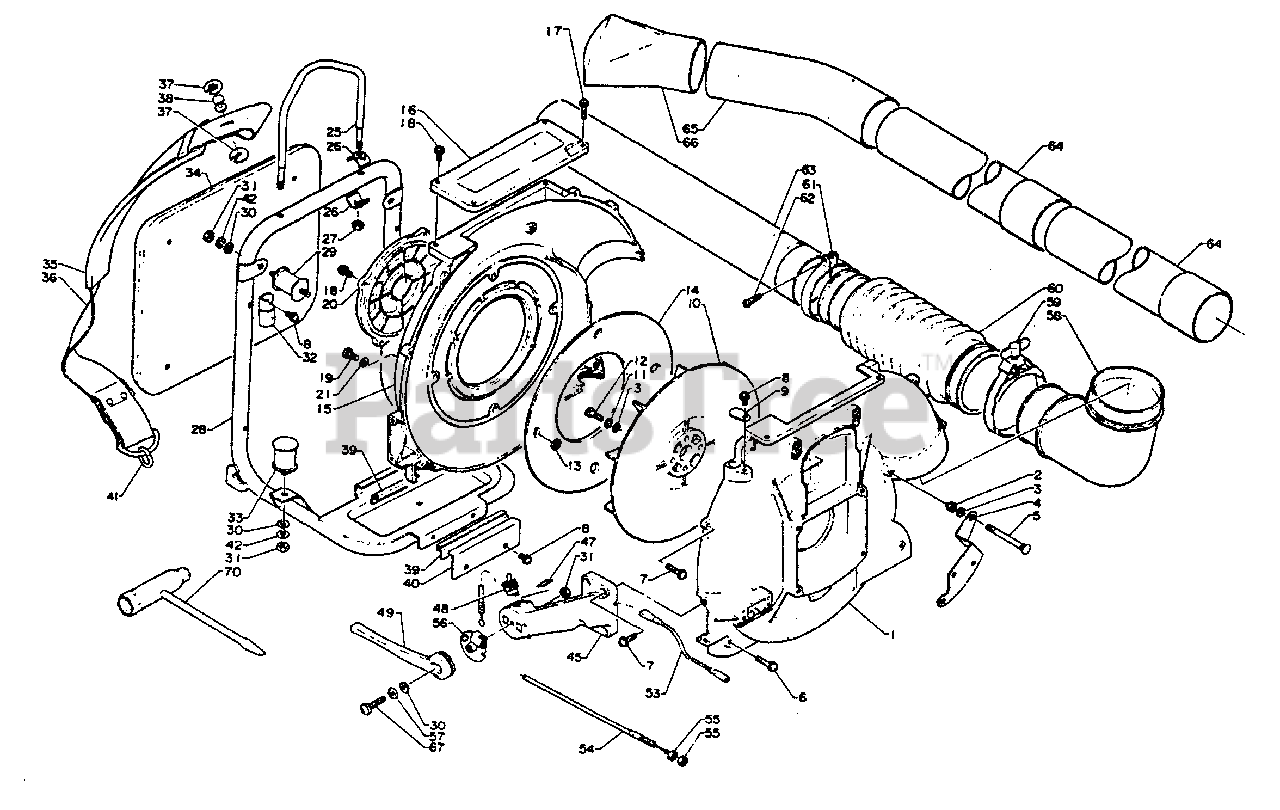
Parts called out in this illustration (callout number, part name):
1	COVER, FAN - OUTER
2	NUT - 5
3	WASHER - 5
4	BRACKET, MUFFLER COVER
5	BOLT, ELBOW
6	SCREW - 5X25
7	SCREW - 5X20
8	SCREW - 5X10
9	PLUG
11	LOCKWASHER - 5
12	BOLT - 5X16
14	SEPARATER
15	COVER, FAN - INNER
16	PLATE
17	SCREW - 6X20
18	SCREW - 6X15
19	BOLT - 5X12
20	GUARD, DEBRIS
21	WASHER - 5
27	LOCKNUT - 6
28	FRAME, BACKPACK
30	WASHER - 6
31	LOCKNUT - 6
32	BRACKET, CUSHION
34	CUSHION
35	BACKPACK STRAP ASSY
36	BACKPACK STRAP ASSY
37	RING, RETAINING
39	CUSHION, FUEL TANK
40	BRACKET, FUEL TANK
41	RING, STRAP
45	MOUNT, THROTTLE LEVER
47	LABEL - STOP
48	IGNITION SWITCH ASSY
49	TRIGGER, THROTTLE
53	LEAD - GROUND
54	CABLE, THROTTLE
57	WASHER
58	TUBE, BLOWER - ELBOW
59	CLAMP
60	TUBE, BLOWER - FLEXIBLE
61	CLAMP
62	SCREW - 5X20
63	TUBE, BLOWER - SWIVEL
64	TUBE, BLOWER - STRAIGHT
65	TUBE, BLOWER - CURVED
66	NOZZLE - FAN HEAD
67	SCREW - 6X25
70	T-WRENCH - 10X19mm
